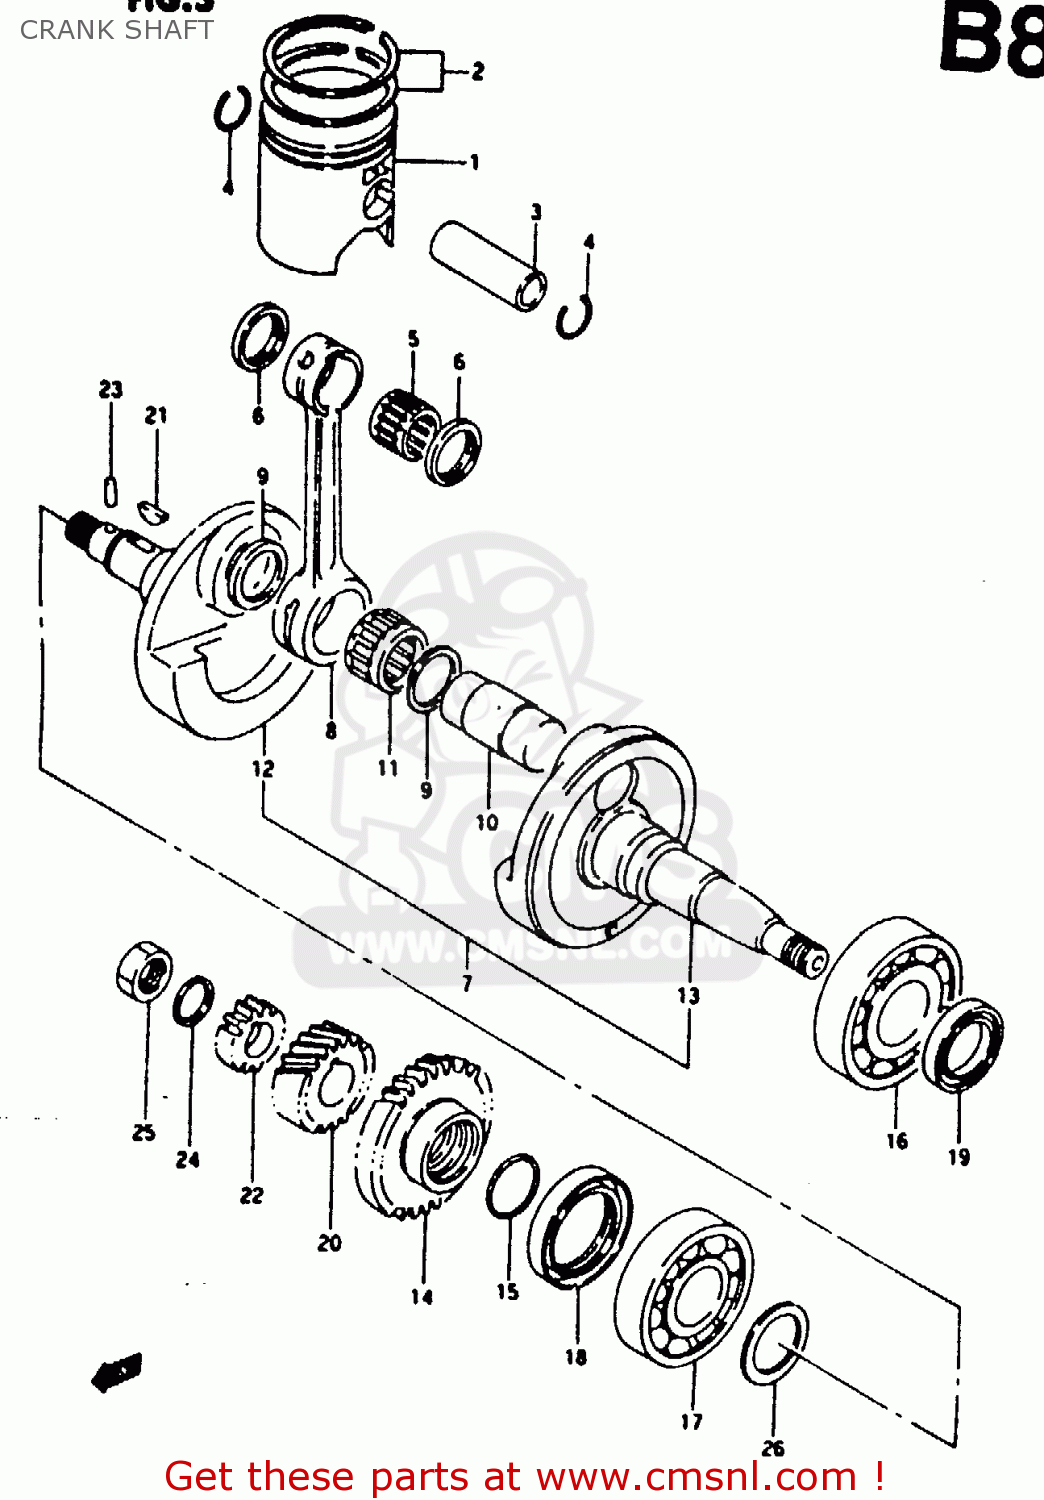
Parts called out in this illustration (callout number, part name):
1	PISTON
2	RING SET,PISTON
3	PIN,PISTON
4	RING,SNAP 16MM
5	BEARING(16X20X17.8)
6	WASHER
7	CRANKSHAFT ASSY
8	ROD,CONNECTING
9	WASHER(22X27.5X1.5)
10	PIN,CRANK
11	ROLLER BEARING (22X28X1
12	CRANKSHAFT, RH
13	CRANKSHAFT, LH
14	GEAR,CRANK BLANCER DRIVE
15	O RING(D:2.3,ID:24.4)
16	BEARING 28X68X18
17	BEARING(25X62X17)
18	SEAL,OIL(36X52X8)
19	SEAL,OIL(25X36X6)
20	GEAR,PRIMARY DRIVE
21	KEY
22	GEAR,WATER PUMP DRIVE
23	PIN
24	WASHER
25	NUT
26	PASTILHA
